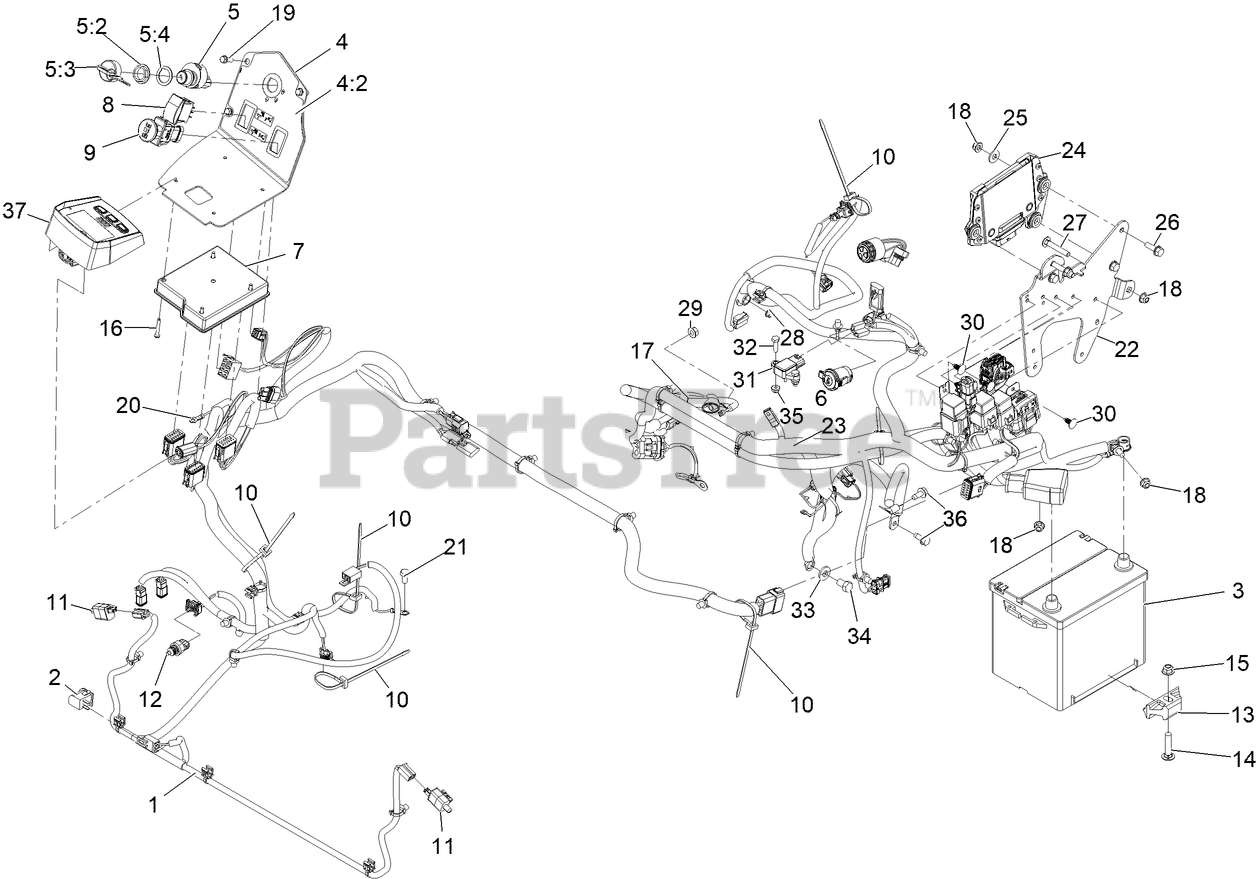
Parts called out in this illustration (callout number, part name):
1	HARNESS-WIRE
2	SWITCH-BAIL
3	Battery-Dry
4	Console ASM
4:2	DECAL-CONTROL PANEL
5	IGNITION SWITCH ASM
5:2	NUT-MOUNTING
5:3	IGNITION KEY SET
5:4	WASHER-BACKUP
6	PORT-POWER, 12V
7	Module-Mcu
9	SWITCH-PTO, SEALED
10	TIE-CABLE
12	SENSOR-TEMPERATURE
13	RETAINER-BATTERY
14	SCREW-CARR
15	NUT-HF, NI
16	SCREW-PPH
17	CABLE-BATTERY
18	NUT-HF, NI
19	SCREW-HWH
20	HARNESS-WIRE, JUMPER
21	BOLT
22	BRACKET-MOUNT, ECU
23	HARNESS-WIRE, YANMAR
24	ECU ASM-SERVICE
25	WASHER-FLAT
26	SCREW-HHF
27	BOLT-CARR
30	PLUG-PLASTIC
31	SENSOR-ATM
32	SCREW-HH
33	WASHER-BELLEVILLE
34	SCREW-HH
36	Screw-HWH 5/16-18 X 3/4 Tf
37	MODULE, LDU
